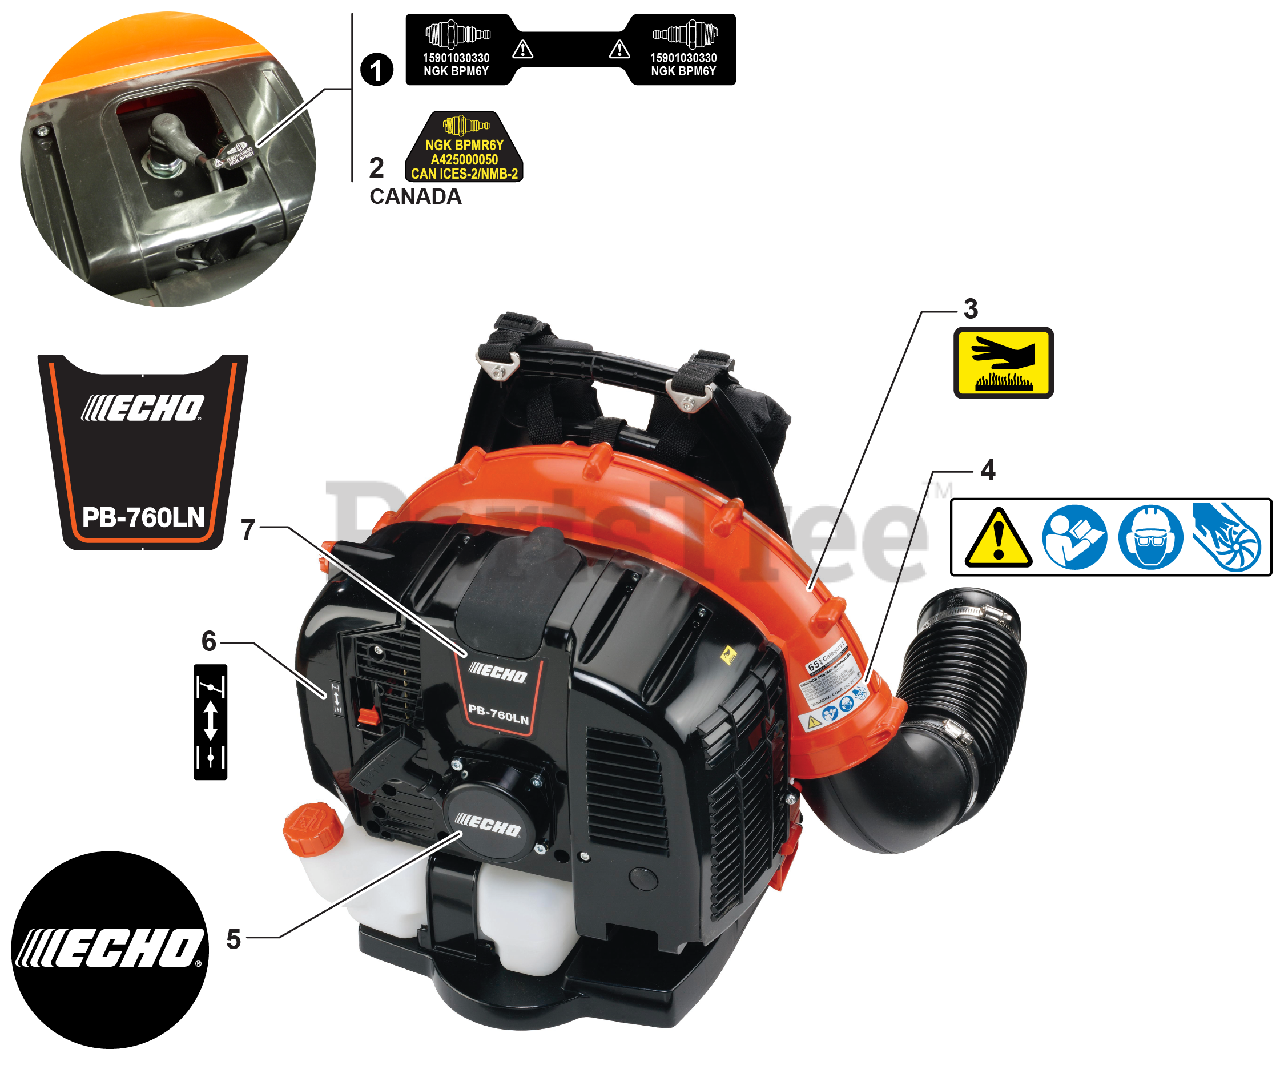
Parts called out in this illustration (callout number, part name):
1	LABEL, SPARK PLUG - BPM6Y
2	LABEL, SPARK PLUG - BPMR6Y
3	LABEL, CAUTION - HOT
4	LABEL, CAUTION - ISO
5	LABEL, ECHO
6	LABEL, CHOKE
7	LABEL, MODEL PB-760LN
